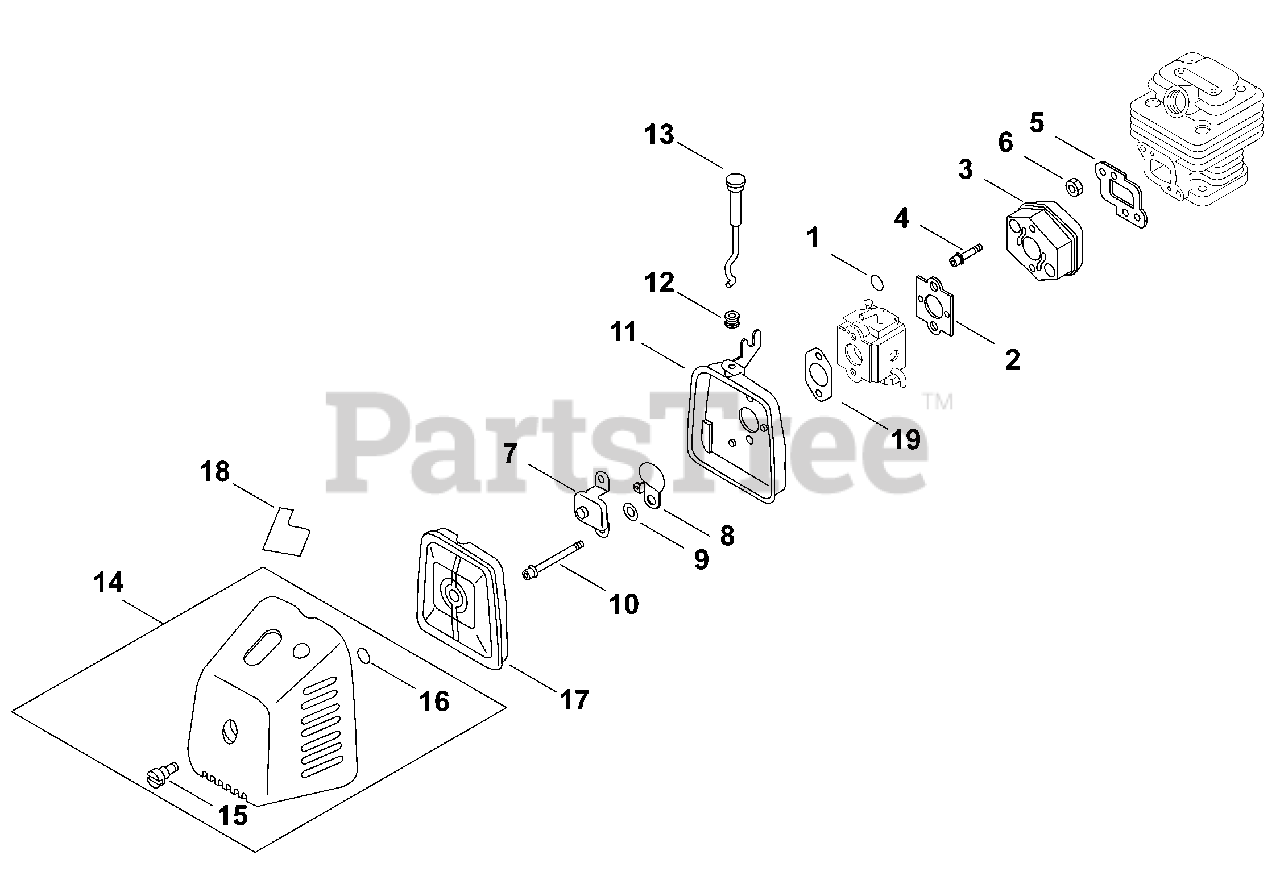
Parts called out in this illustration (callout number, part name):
2	GASKET, INTAKE
3	INSULATOR, INTAKE
4	BOLT 5×25
5	GASKET, INTAKE
6	NUT M5
8	SHUTTER, CHOKE
9	WASHER 5.2×8×0.8T
10	SCREW 5×57
11	CASE, AIR FILTER
12	GROMMET, CHOKE
13	KNOB, CHOKE
14	COVER ASSY, AIR FILTER
17	FILTER, AIR
18	LABEL, CHOKE
19	GASKET, INTAKE
